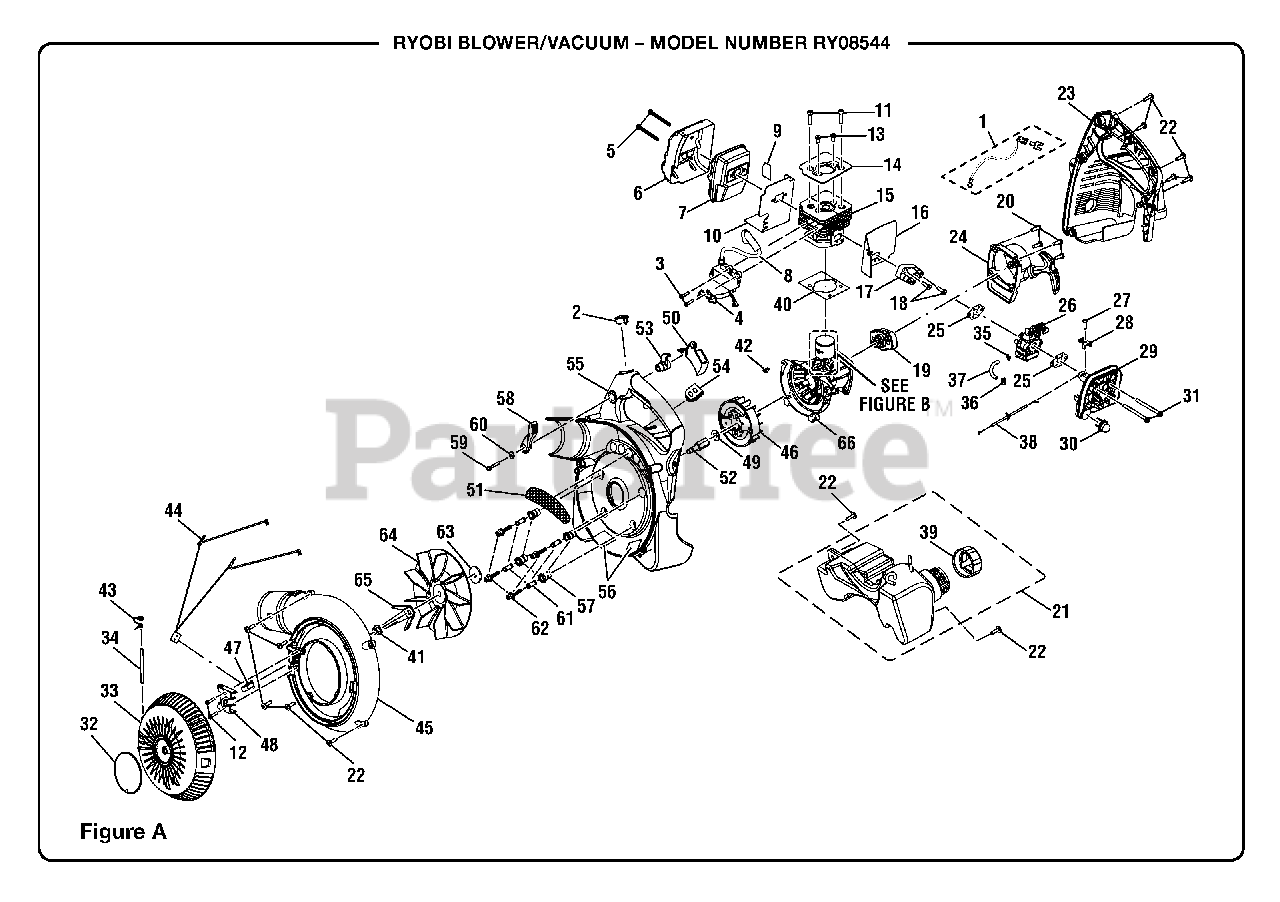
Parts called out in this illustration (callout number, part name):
1	Grounding Wire Kit
3	Screw (M4 X 22 mm)
4	Lead Assembly
5	Screw (M5 X 50 mm)
6	Heat Shield
7	Muffler Assembly
8	Coil & Boot Assembly
9	Heat Shield
10	Gasket Muffler
11	Screw (M5 X 22 mm)
12	Screw (#8-14 X 16.3 mm)
13	Screw & Washer (M5 X 10 mm)
14	Plate for Cylinder
15	Cylinder
16	Insulator Gasket
17	Insulator
18	Screw & Washer (M5 X 22 mm)
19	Pulley Assembly
20	Screw (M5 X 16 mm)
21	Fuel Tank Assembly
22	Screw (#10-14 X 7/8 in.)
23	Engine Shroud Housing
24	Starter Assembly
25	Carburetor Gasket
26	Carburetor (Walbro WYC-8)
27	Screw (M4 X 1.75 X16 mm Pan Hd.)
28	Clip-throttle Cable
29	Air Box Base
30	Primer Assembly
31	Screw (M5 X 60 mm)
32	Vacuum Door Cover
33	Vacuum Door
34	Hinge Pin
35	Clip-hose (Id 4.9)
36	Clip-hose
37	Tubing Rubber
38	Cable Assembly
39	Fuel Cap Assembly
40	Cylinder Gasket
41	Retaining Washer Nut
42	Key Woodruff (S43C)
43	Vacuum Door Hinge Spring
44	Vacuum Door Kill Switch
45	Outer Volute Housing
46	Fly-wheel Assembly
47	Kill Switch Activator Lever
48	Vacuum Door Hinge
49	Washer (2 mm)
51	Metal Mesh
52	Crank Shaft Extension
53	Trigger Lock
54	Rubber Grommet
55	Housing Inner Volute
56	Heat Shield
57	Vibration Isolator
58	Cruise Lever
59	Screw (#8-14 X 25 mm)
61	Bushing Sleeve
62	Screw (M5 X 8 mm Cap Hd.)
63	Washer-fan Spacer
64	24.5 Cc Blower Fan
65	Blade-mulder
66	Crankcase Assembly
